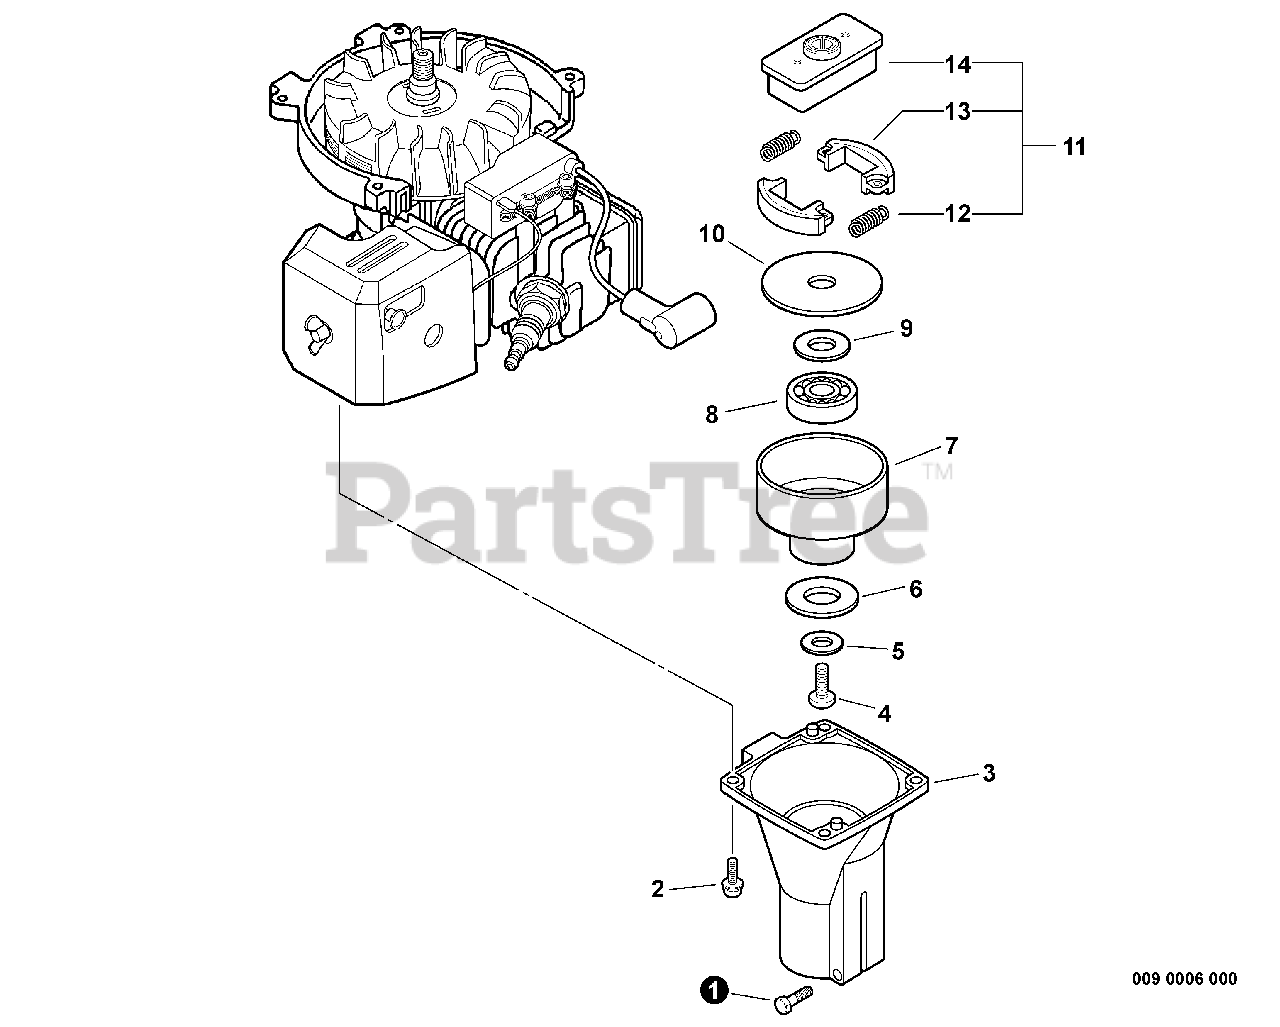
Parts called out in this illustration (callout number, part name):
1	BOLT - 5X25
2	SCREW - 4X18
3	CASE, CLUTCH
4	SCREW - 6X12
5	WASHER, CLUTCH
6	WASHER, CLUTCH
7	DRUM, CLUTCH
8	BEARING, BALL - 6000
9	WASHER - 10
10	PLATE, CLUTCH
11	CLUTCH ASSY
12	SPRING, CLUTCH
13	SHOE, CLUTCH
14	HUB, CLUTCH
